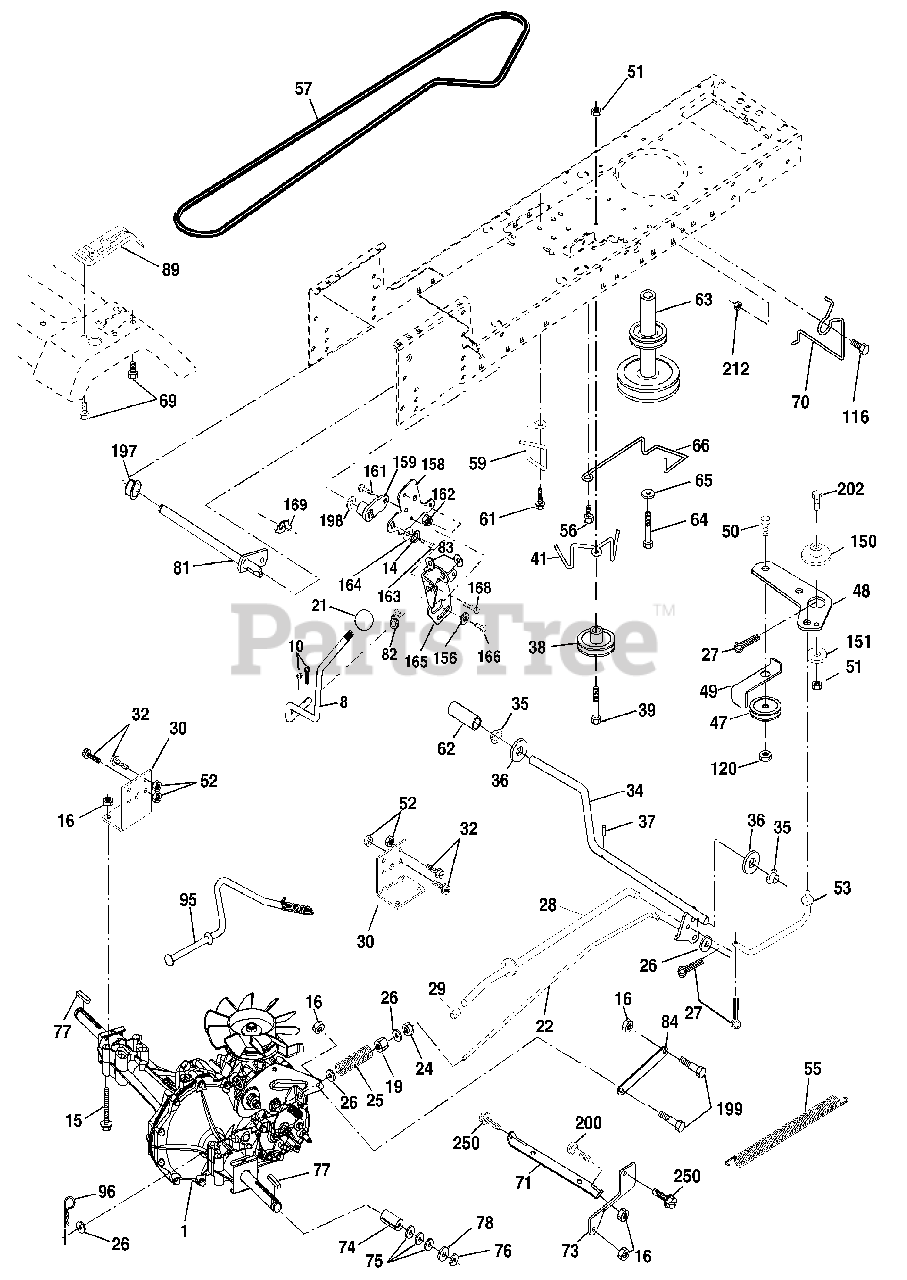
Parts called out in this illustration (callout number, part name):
8	Rod Shift Hydro LT
10	Pin Cotter 1/8 x 1 CAD
14	Washer Lock Hvy Helical
15	Bolt, Hex FLGHD 5/16-18 Gr. 5
16	Nut Lock Hex W/Ins 5/16-18 Unc P
19	Nut Lock Hex W/Wsh 3/8-16 Unc
21	Knob, Round 1/2-13
22	Rod, Brake Hydro
24	Nut
25	Spring, Brake Rod
26	Washer
27	Pin Cotter 1/8 x 3/4 CAD.
28	Rod, Parking Brake
29	Cap, Parking Brake
30	Bracket, Transaxle
32	Bolt Hex Hd 5/16-18 Unc x 3/4
34	Shaft, Foot Pedal
35	Bearing, Nylon
36	Washer
37	Pin, Roll
38	Pulley, Composite
39	Bolt, Fin Hex 3/8-16 x 3
41	Keeper, Belt Idler
47	Pulley, Idler, V-Groove
48	Bellcrank Clutch Grnd Drv STL
49	Retainer, Belt
50	Bolt
51	Nut Crownlock 3/8-16 UNC
52	Nut Crownlock 5/16-18 UNC
53	Link, Clutch
55	Spring, Return, Clutch
56	Screw
57	V-Belt, Ground Drive
59	Keeper, Center Span
61	Screw 3/8-16 x .875
62	Cover, Pedal
63	Pulley, Engine
64	Bolt, Hex
65	Washer
66	Keeper Belt Engine
69	Screw
70	Guide Belt
71	Strap Torque Lh Hydro
73	Strap Torque Rh Hydro
74	Spacer, Axle
75	Washer 25/32 x 1-1/4 x 16 Gauge
76	E-Ring
77	Key, Square
78	Washer 25/32 x 1-5/8 x 16 Gauge
81	Shaft Asm. Cross Hydro
82	Spring Torsion T/A
83	Washer 17/32 x 3/4 x 16 Ga.
84	Link Transaxle
89	Console, Hydro
95	Control Asm Bypass Hydro
96	Retainer Spring 1" Zinc/Cad
116	Bolt RDHD SQNK 3/8-16 UNC x 1
120	Nut Lock Flg 3/8-16 Unc
150	Spacer Retainer
151	Washer 13/32 x 2 x 10 Ga.
156	Washer Srrted 5/16 ID x 1.125
158	Bracket Shift Mount
159	Hub Tapered Flange Shift Lt
161	Bolt Rdhd Sqnk 1/4-20 x 3/4 Gr 5
162	Nut Crownlock 1/4-20 Unc
163	Bolt Hex Fin 1/4-20 Unc x 1 Gr 5
164	Washer 5/8 x .281 x 10 Ga
165	Bracket Pivot Lever
166	Screw 5/16-18 x 5/8
168	Bolt Shoulder 5/16-18 x .561
169	Plate Fastening Lt
197	Nyliner Snap-In 5/8" ID
198	Washer Nyl 7/8 ID x .105
199	Bolt Shoulder 5/16-18 Unc
200	Bolt Rdhd Sqnk 5/16-18 Unc x 1
202	Bolt Carr Sh 3/8-16 x 1-3/4 Gr 5
212	Nut Hex flange Lock
250	Screw Thdrol. 3/8-16 x .75
